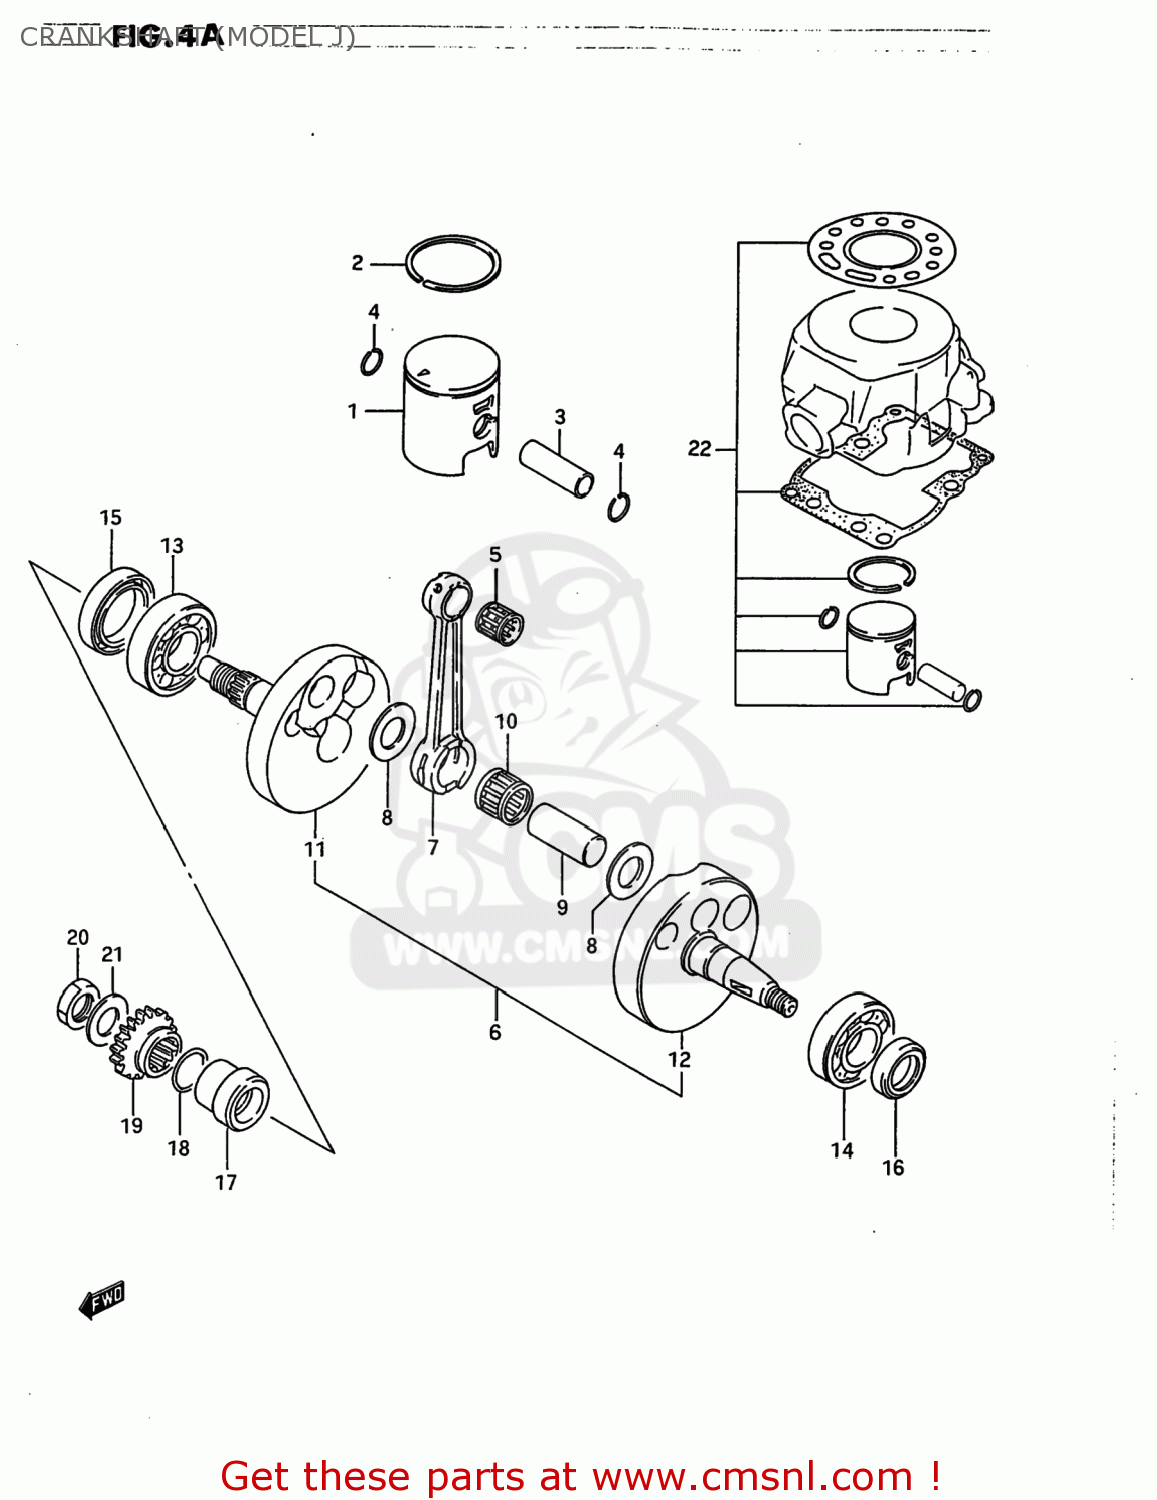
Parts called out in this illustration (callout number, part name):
1	PISTON
2	RING,PISTON
3	PIN,PISTON
4	RING,SNAP 14MM
5	BEARING(14X18X16)
6	CRANKSHAFT ASSY
7	ROD,CONNECTING
8	WASHER (18X23.5X1.5)
9	PIN,CRANK
10	BEARING
11	CRANKSHAFT,R
12	CRANKSHAFT,L
13	BEARING(20X52X15)
14	BEARING(20X47X14)
15	SEAL,OIL(32X44X8)
16	SEAL,OIL(18X30X8)
17	SPACER,PRIMARY DRIVE GEAR
18	O RING(D:2.4,ID:19.8)
19	GEAR,PRIMARY DRIVE
20	NUT
21	WASHER
22	PISTON SET (STD)
